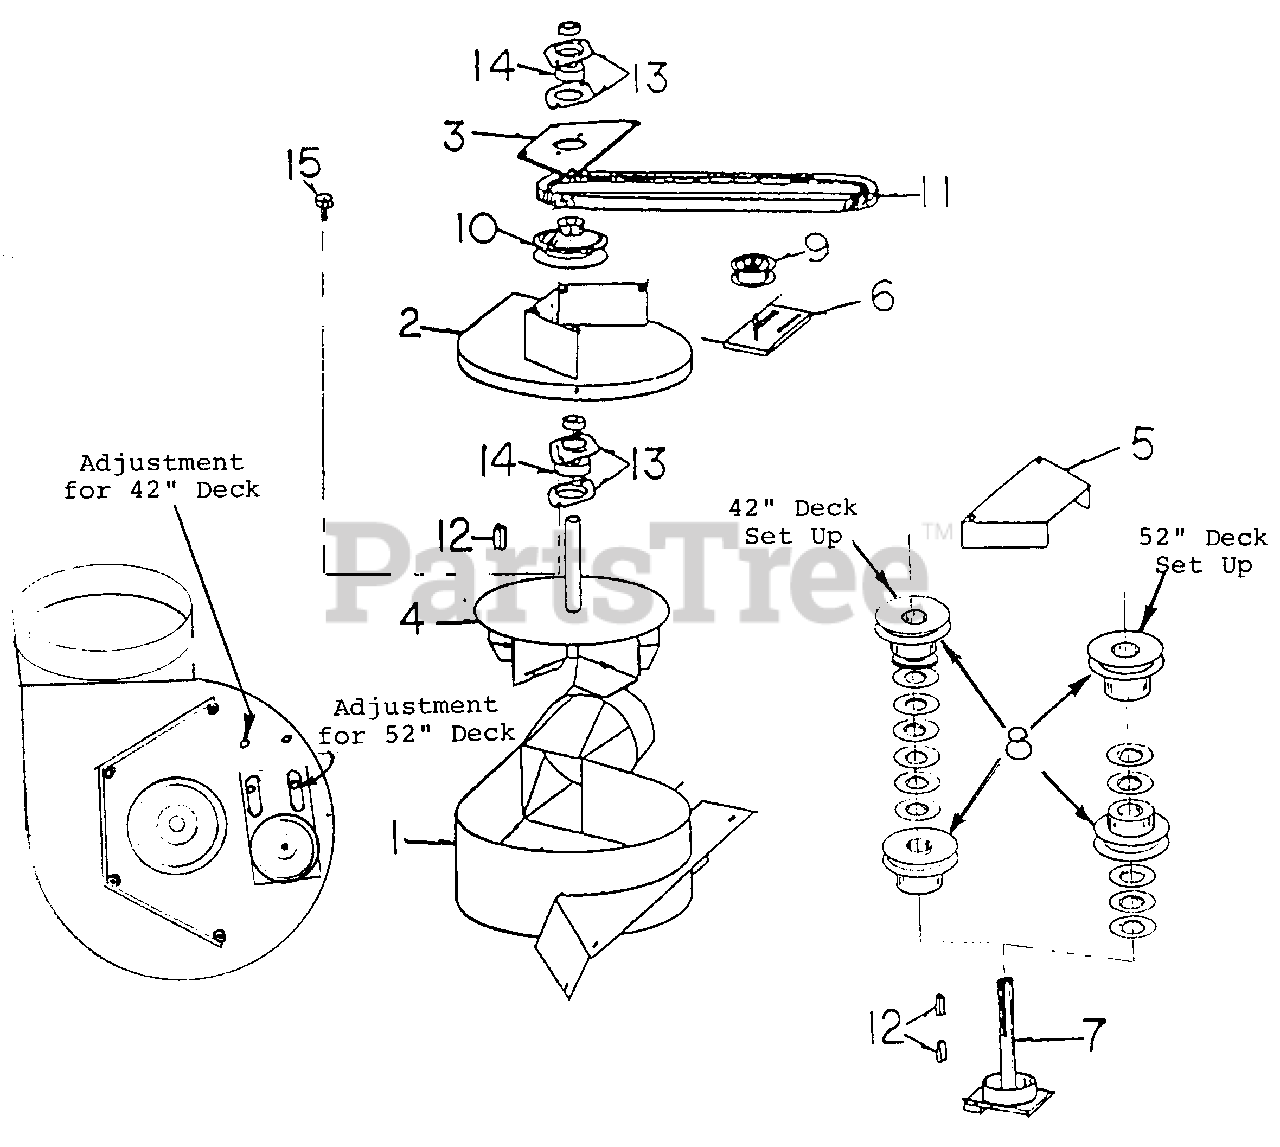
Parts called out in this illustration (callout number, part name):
1	BLOWER HOUSING
2	BLOWER CAP
3	BLOWER BEARING PLATE
4	BLOWER BLADE ASSEMBLE
5	BLOWER GUARD
6	BELT TIGHTENER
7	SHAFT, SPINDLE LONG
8	PULLEY, SPINDLE
9	PULLEY, IDLER
10	PULLEY, BLOWER
11	BELT, G1642 & G1842 BLOWER
11	BELT, G1652 & G1852 BLOWER
13	FLANGE
14	3/4 BEARING
15	4 5/16-18 x 5/8 LONG BOLT
